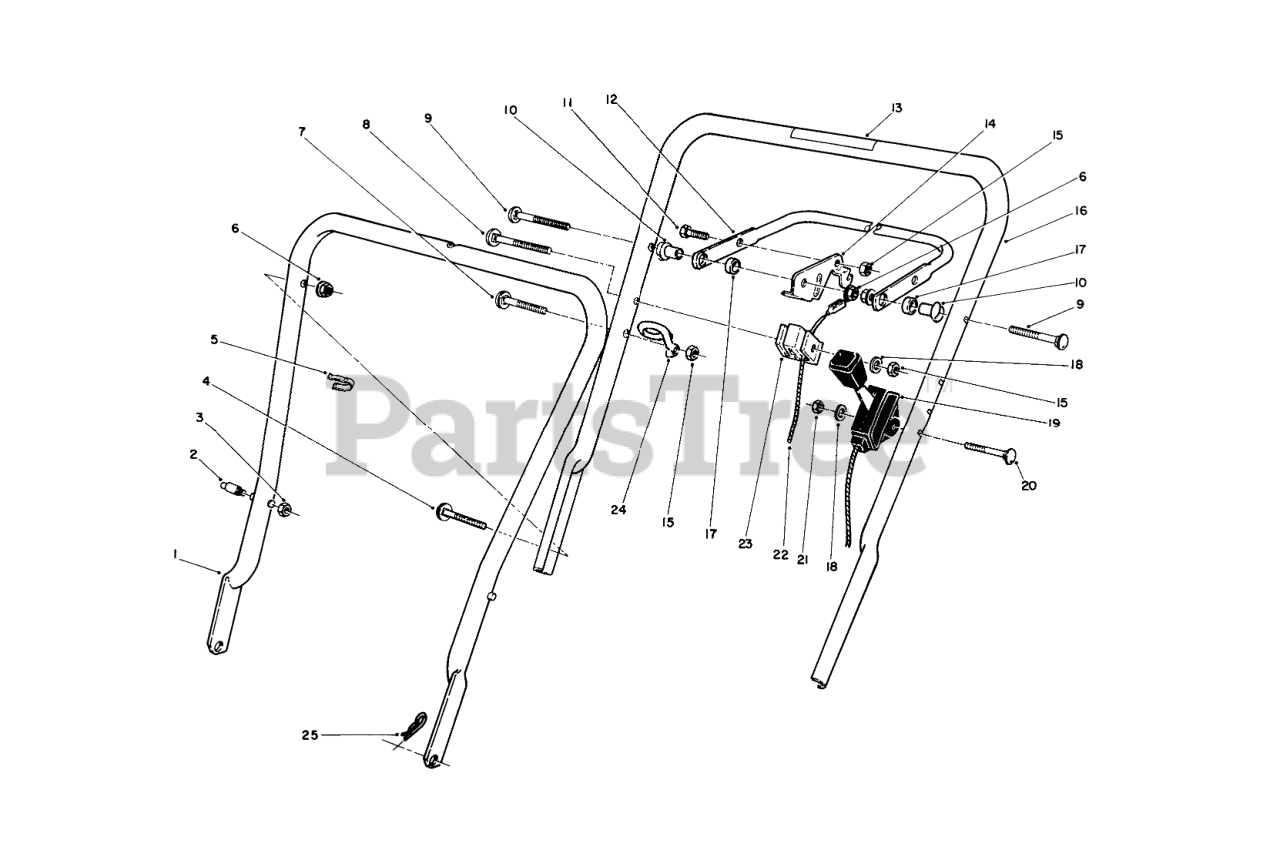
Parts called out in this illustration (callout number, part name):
1	LOWER HANDLE ASM
2	HANDLE PIN
3	NUT-LOCK, NI
4	SCREW
6	NUT-LOCK, NI
7	HANDLE SCREW
8	HANDLE SCREW
9	5/16-18 X 2 HNDLE SCREW
10	SPACER-SUPPORT
11	SCREW-HH
12	Bar-Control
13	Decal-Danger
14	Control Lever
15	NUT-LOCK, NI
16	Handle-Upper (Incl. Ref. #13)
17	SPACER-NYLON
18	WASHER-FLAT
19	Control Throttle (Bend Type #1)(Sheath Lg. 45")(Wire Lg. 2-3/16")
20	SCREW-HANDLE
21	NUT-LOCK, NI
22	BRAKE CABLE
23	SUPPORT-CABLE
24	Guide
25	PIN-COTTER, HAIR
